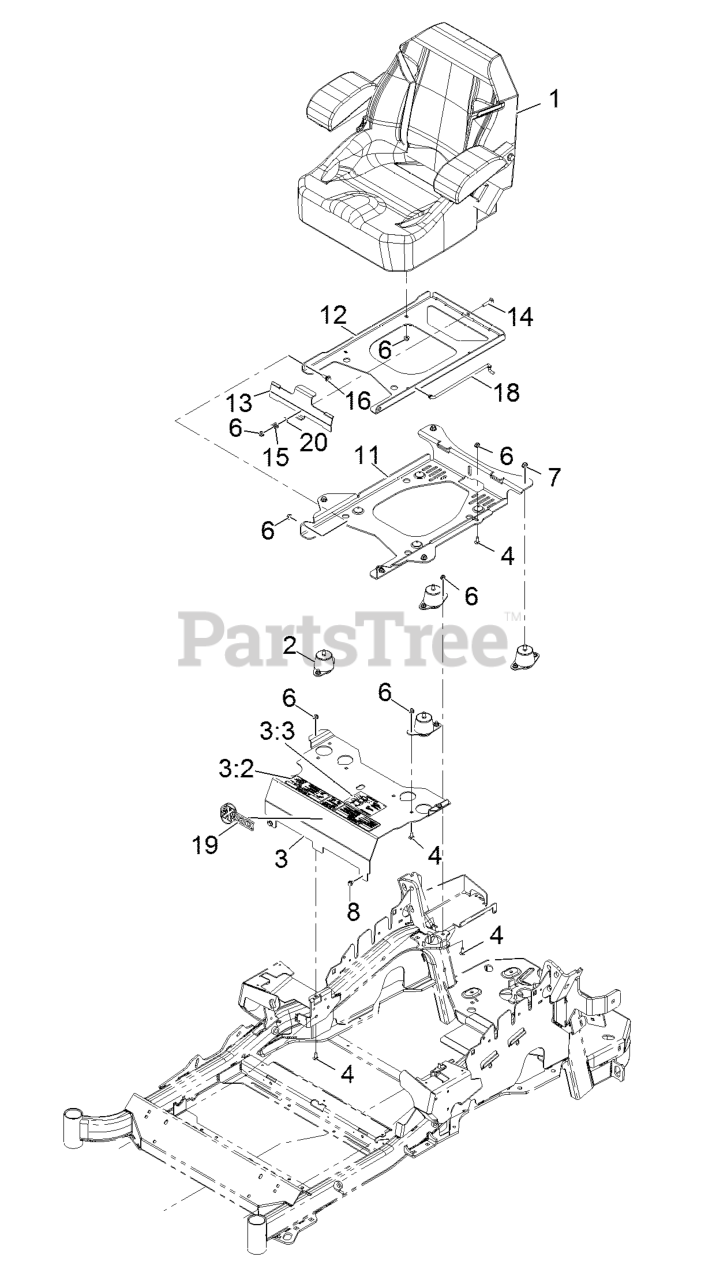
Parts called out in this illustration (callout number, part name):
2	ISOLATOR-SEAT
3	MOUNT-SEAT
3:2	DECAL-CONSOLE
3:3	DECAL-SERVICE AID
4	SCREW-CARR
6	NUT-HF, NI
7	NUT-HF, NI
11	PLATE-TILT, SEAT SUPPORT
12	PLATE-FRAME, SEAT
13	PLATE-LATCH, SEAT
14	BOLT-CARR
15	SPRING-COMPRESSION
16	SCREW-SHOULDER
18	ROD-PROP
20	WASHER-PLAIN
